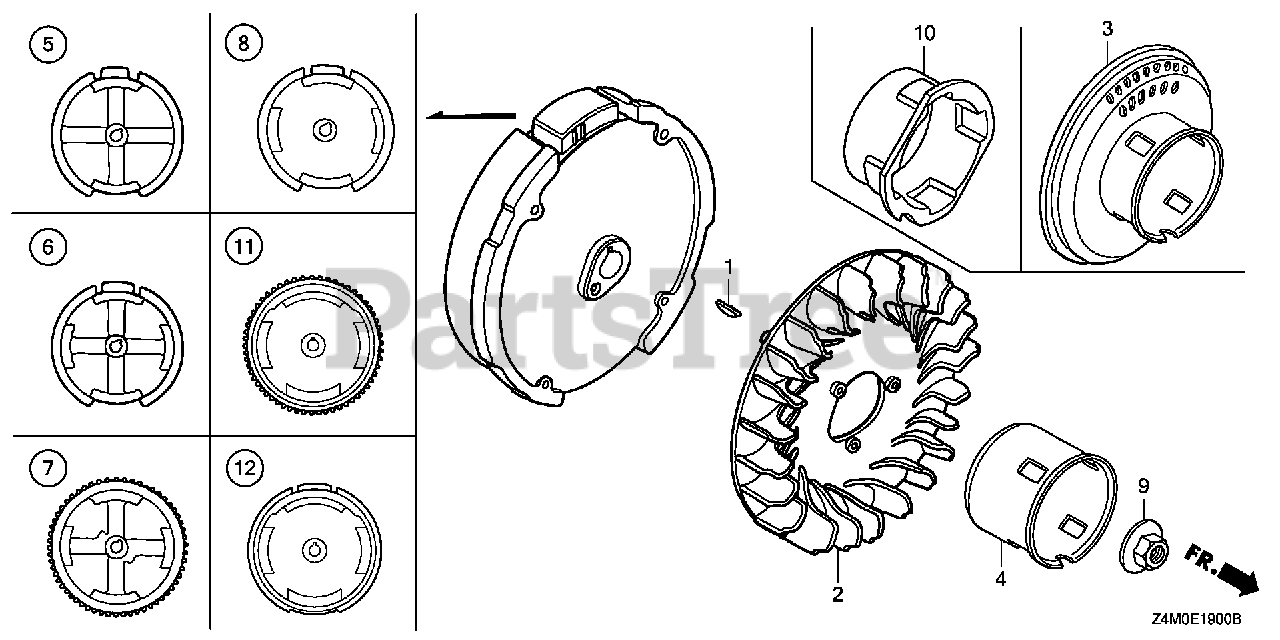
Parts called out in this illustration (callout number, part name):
1	KEY, SPECIAL WOODRUFF (25X18)
2	FAN, COOLING
4	PULLEY, STARTER
9	NUT, SPECIAL (14MM)
12	FLYWHEEL (4POLE-3MAGNET)
